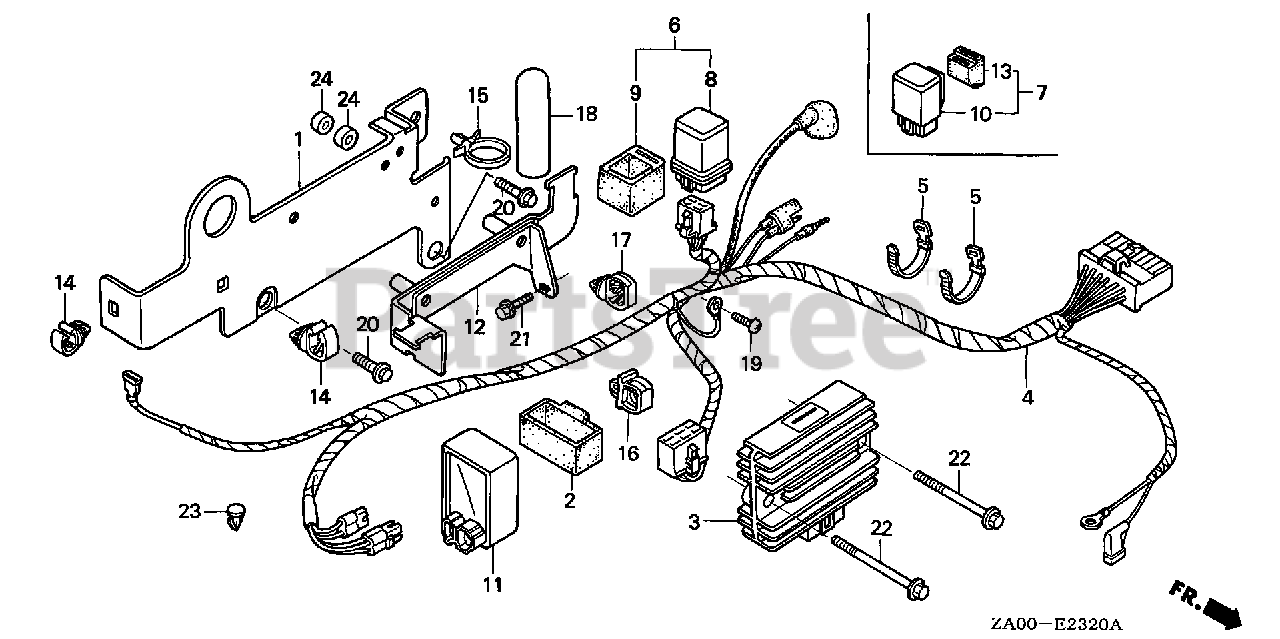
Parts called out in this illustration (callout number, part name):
1	HOOK, ENGINE
2	RUBBER, IGNITION CONTROL (Honda Code 1772458). MODULE
3	RECTIFIER ASSY., REGULATOR
4	WIRE HARNESS ASSY. (10A)
5	BAND, WIRE Use up to Frame SN 1001879.
7	RELAY ASSY., CONTROL (10A)
10	RELAY (10A)
11	ALERT UNIT
12	BRACKET, ALERT UNIT
13	SUSPENSION, STARTER RELAY (Honda Code 2486298). (TATEISHI)
14	CLIP, WIRE HARNESS
15	CLIP, WIRE HARNESS
17	CLIP, HARNESS (10MM)
18	TUBE, CORD (22MM)
19	SCREW, PAN (5X12)
20	BOLT, FLANGE (8X20) Use up to Engine SN 1609606.
21	BOLT, FLANGE (6X12) Use up to Engine SN 1543277.
22	BOLT, FLANGE (6X45)
